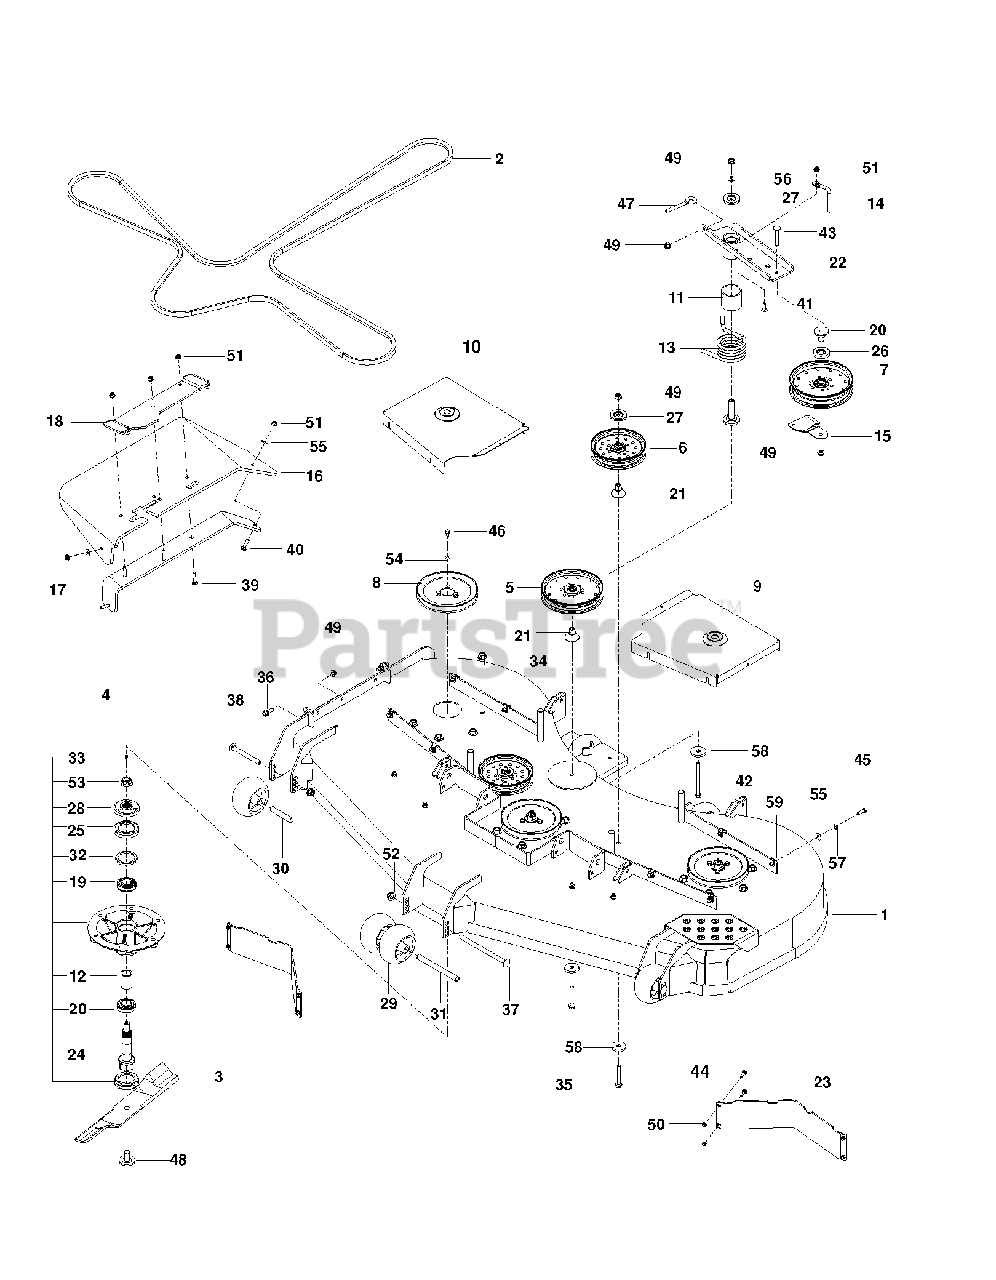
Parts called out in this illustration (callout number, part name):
1	DECK W/SAFETY DECALS 72"
2	BELT, "B", 201
4	SPINDLE ASM. 10"
5	PULLEY - 7" NARROW
6	PULLEY IDLER, 6" NARROW
7	PULLEY - IDLER 7"
9	SHIELD, 72 RT
10	SHIELD BELT LH 72 BLUE
12	SPACER - BEARING
15	BELT GUIDE, BLK
16	CHUTE, DISCHARGE 60-72
17	BRKT - CHUTE SUPPORT BLACK
18	BRKT - CHUTE MTG BLACK
19	BEARING - 206KRR8
20	BEARING, IDLER ARM
21	BEARING, IDLER PIVOT
24	SHAFT - SPINDLE
25	CUP - DEBRIS
26	SHIELD, DUST
27	DUST SHIELD
28	HUB - PULLEY
29	ROLLER, GAUGE .635 BORN
30	TUBE, ROLLER AXLE
31	TUBE, ROLLER AXLE LONG
32	V-RING, 55MM
33	ZERK
35	HHFS 3/8-16 X 2 3/4
36	HHFS 3/8-16 X 1 GRD 5 ZD
37	RHSNB 1/2-13 X 8 GR5 ZD
38	RHSNB 1/2-13 X 4.75 GR5 ZD
39	RHSNB 5/16-18 X 1-1/2 GR 5 ZD
40	BOLT, CARRIAGE 5/16X1-1/4
41	RHSSNB 5/16C X 1.0
42	HCS 3/8-16 X 4-1/2 GR 8 ZD
43	CARRIAGE BOLT 3/8-16 X
45	HCS 5/16C X 1
46	HCS 5/16-18 X 1/2 GR 5 ZD
48	BLADE BOLT/WASHER
49	NUT 3/8-16 HEX FLG NYLOC ZD
50	NUT 1/4-20 NYLOC
51	5/16-18 NYLOC FLANGE NUT
52	NUT, 1/2-13 HEX FLG NYLOC ZD
53	NUT FLANGE 3/4-16
54	WASH 5/16 DISC SPRING ZD
55	WASHER 5/16 FLAT
56	WASHER, 3/8 THICK
57	WASHER 5/16 LOCK
58	SPINDLE WASHER
59	U-CLIP 5/16-18 NUT RETAINER
